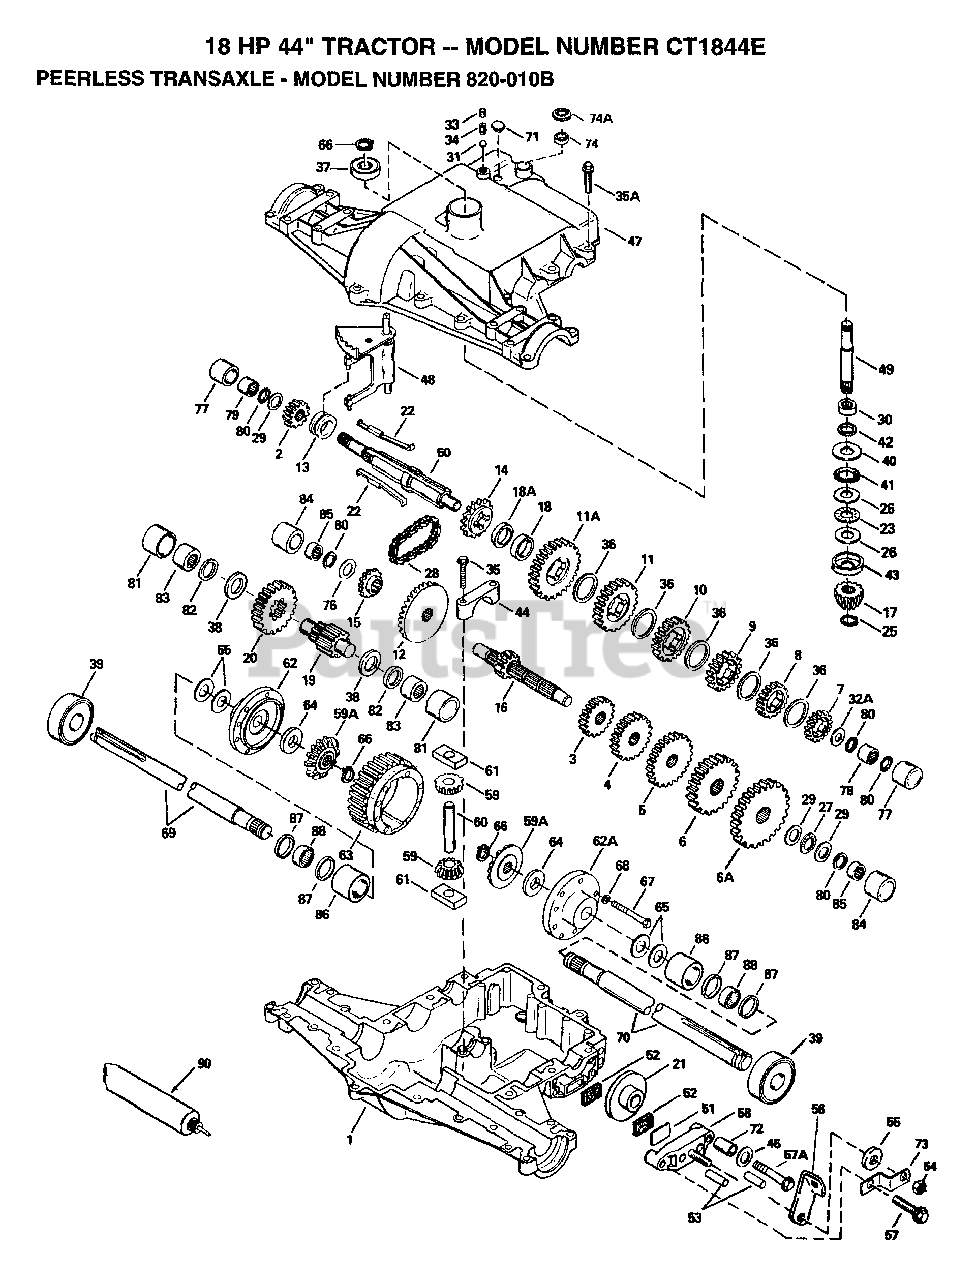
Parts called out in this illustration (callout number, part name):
1	CASE TRANSAXLE
2	GEAR, SPUR, 15T
3	GEAR, SPUR, 12 TEETH
4	GEAR, SPUR, 15T
5	GEAR, SPUR, 20T
6	GEAR, SPUR, 28T
6A	GEAR, SPUR, 31T
7	GEAR, SPUR, 19 TEETH
8	GEAR, SPUR, 22T
9	GEAR, SPUR, 30T
10	GEAR, SPUR, 35T
11	GEAR, SPUR, 37 TEETH
11A	GEAR, SPUR, 41T
12	GEAR BEVEL, 33T
13	COLLAR SHIFT
14	SPROCKET 18T (REV)
15	SPROCKET 9T
16	SHAFT COUNTER
17	BEVEL PINION, 13T
18	SPACER, .350/.340 THICK
18A	SPACER, .276/.268 THICK
19	SHAFT, OUTPUT, 9T
20	GEAR, OUTPUT, 35T
23	BEARING THRUST
25	RETAINING RING
26	WASHER THRUST
27	THRUST BEARING
28	CHAIN, ROLLER
29	WASHER THRUST
30	BEARING NEEDLE
31	BALL STEEL, 5/16" DIA.
32A	WASHER, THRUST
33	SCREW, 3/8-16 X 3/8"
35	SCREW, 1/4-20 X 1-1/4
35A	SCREW HEX HD 5/16-18 X 1-1/4
36	WASHER THRUST
37	BEARING BALL
38	WASHER THRUST
39	BEARING BALL
42	OIL SEAL 3/4
43	WASHER CUPPED
44	BEARING CAP
45	WASHER FLAT
47	COVER TRANSAXLE
48	ROD AND FORK ASSY SHIFT
49	SHAFT INPUT
50	SHAFT BRAKE
51	PLATE BRAKE PAD
54	LOCKNUT 5/16-24
55	WASHER, FLAT
56	LEVER BRAKE
57	SCREW, 1/4-20 X 1-1/4
57A	SCREW, 1/4-20 X 1-1/4
57A	SCREW FLNG HEX 1/4-20 X 2-1/4
58	HOLDER BRAKE PAD
59	PINION, 10T
61	BLOCK DRIVE
62	CARRIER DIFF THREADED HOLES
62A	CARRIER DIFF
63	GEAR, RING, 31T
65	WASHER THRUST
67	SCREW, 1/4-20 X 2-1/4
68	WASHER LOCK 1/4
69	AXLE, 12-5/16" LONG
70	AXLE, 16-3/16" LONG
71	PLUG, THRDED, 9/16-18
73	BRKT BRAKE LEVER
78	BEARING NEEDLE
79	BEARING NEEDLE
81	SLEEVE STEPPED
82	RING SQ CUT
83	BEARING NEEDLE CAPPED
84	SLEEVE STEPPED
85	BEARING NEEDLE CAPPED
86	SLEEVE STEPPED
87	RING SQ CUT
88	BEARING NEEDLE
90	GREASE BENTONITE, 32 OZ.
